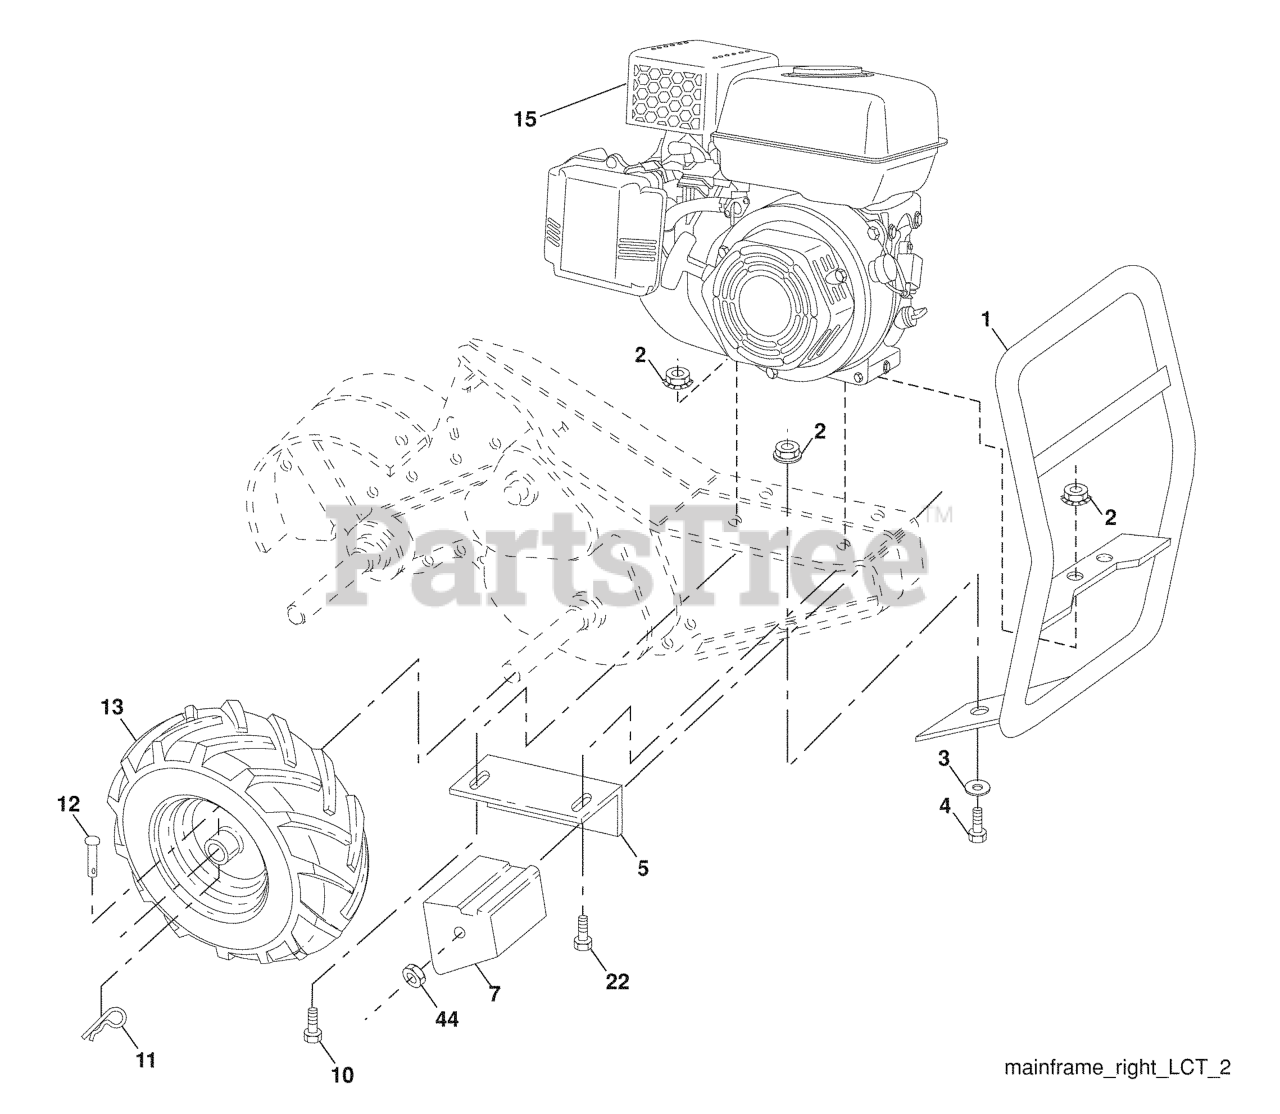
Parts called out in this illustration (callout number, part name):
1	RP.BUMPER.ASM.TILLER.
2	LOCKNUT-FLANGE 5/16-18
3	WASHER
4	BOLT
5	DNO BRACKET RH CRT
6	COUNTERWEIGHT, RH
7	BOLT
8	RETAINER M
9	RIVET,DRILLED
11	RIM.ASM.6".SILVER
12	VALVE STEM LT
14	BOLT, HEX 5/16-18X1-3/4
